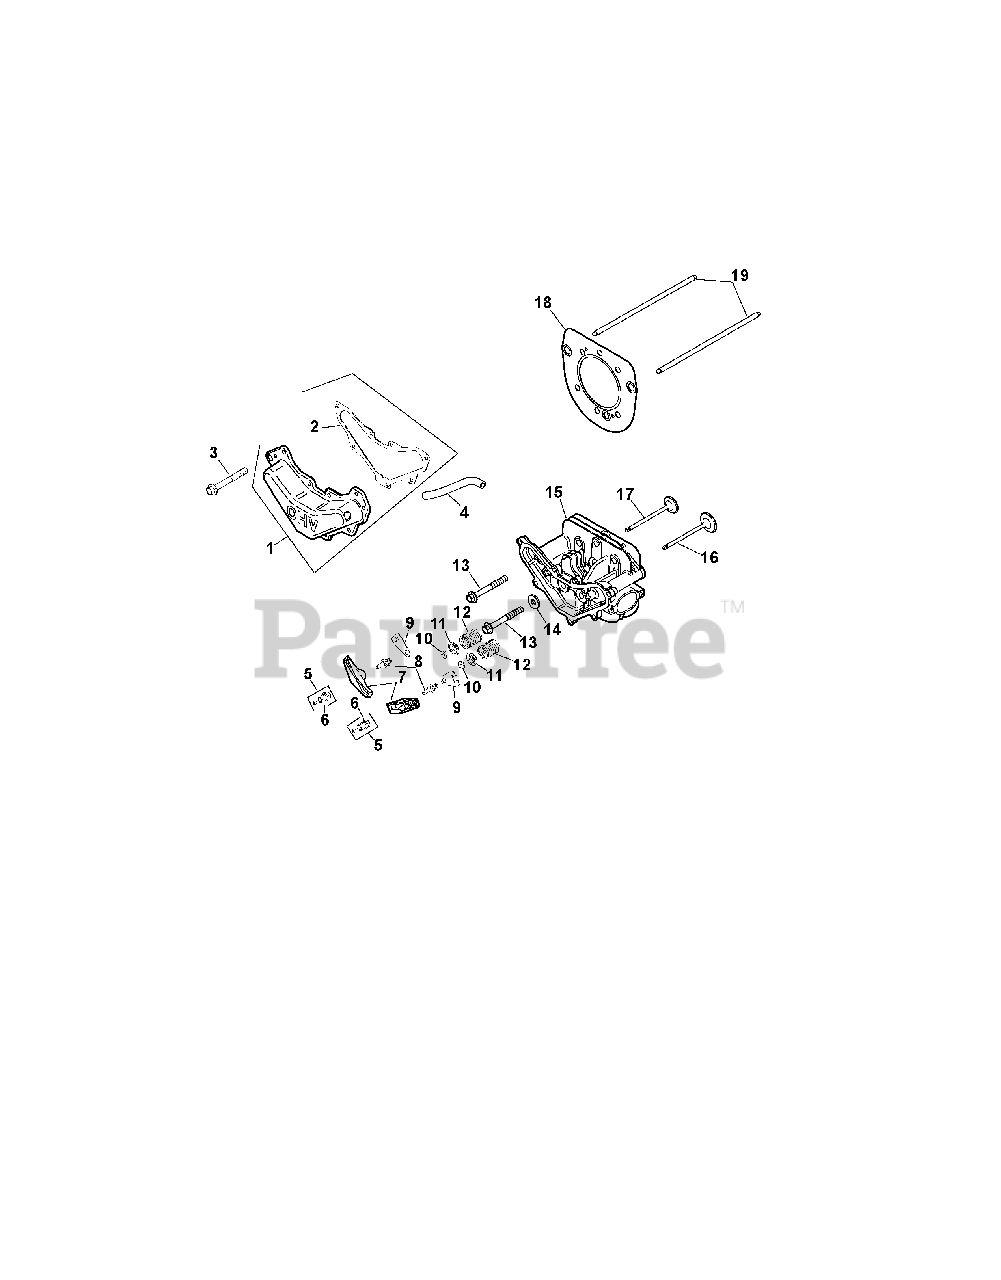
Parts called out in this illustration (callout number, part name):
1	Valve Cover Kit
2	Valve Cover Gasket
3	Hex Flange Screw (M6 x 1.0 x 20)
4	Breather Hose
5	Rocker Arm Pivot Kit
8	Rocker Pivot Set Screw
9	Push Rod Guide Plate
11	Valve Spring Cap
13	Hex Flange Screw (M10 x 1.5 x 37)
14	1/2" Flat Washer
15	Cylinder Head
16	Exhaust Valve
18	Cylinder Head Gasket Repair Kit
19	Push Rod
